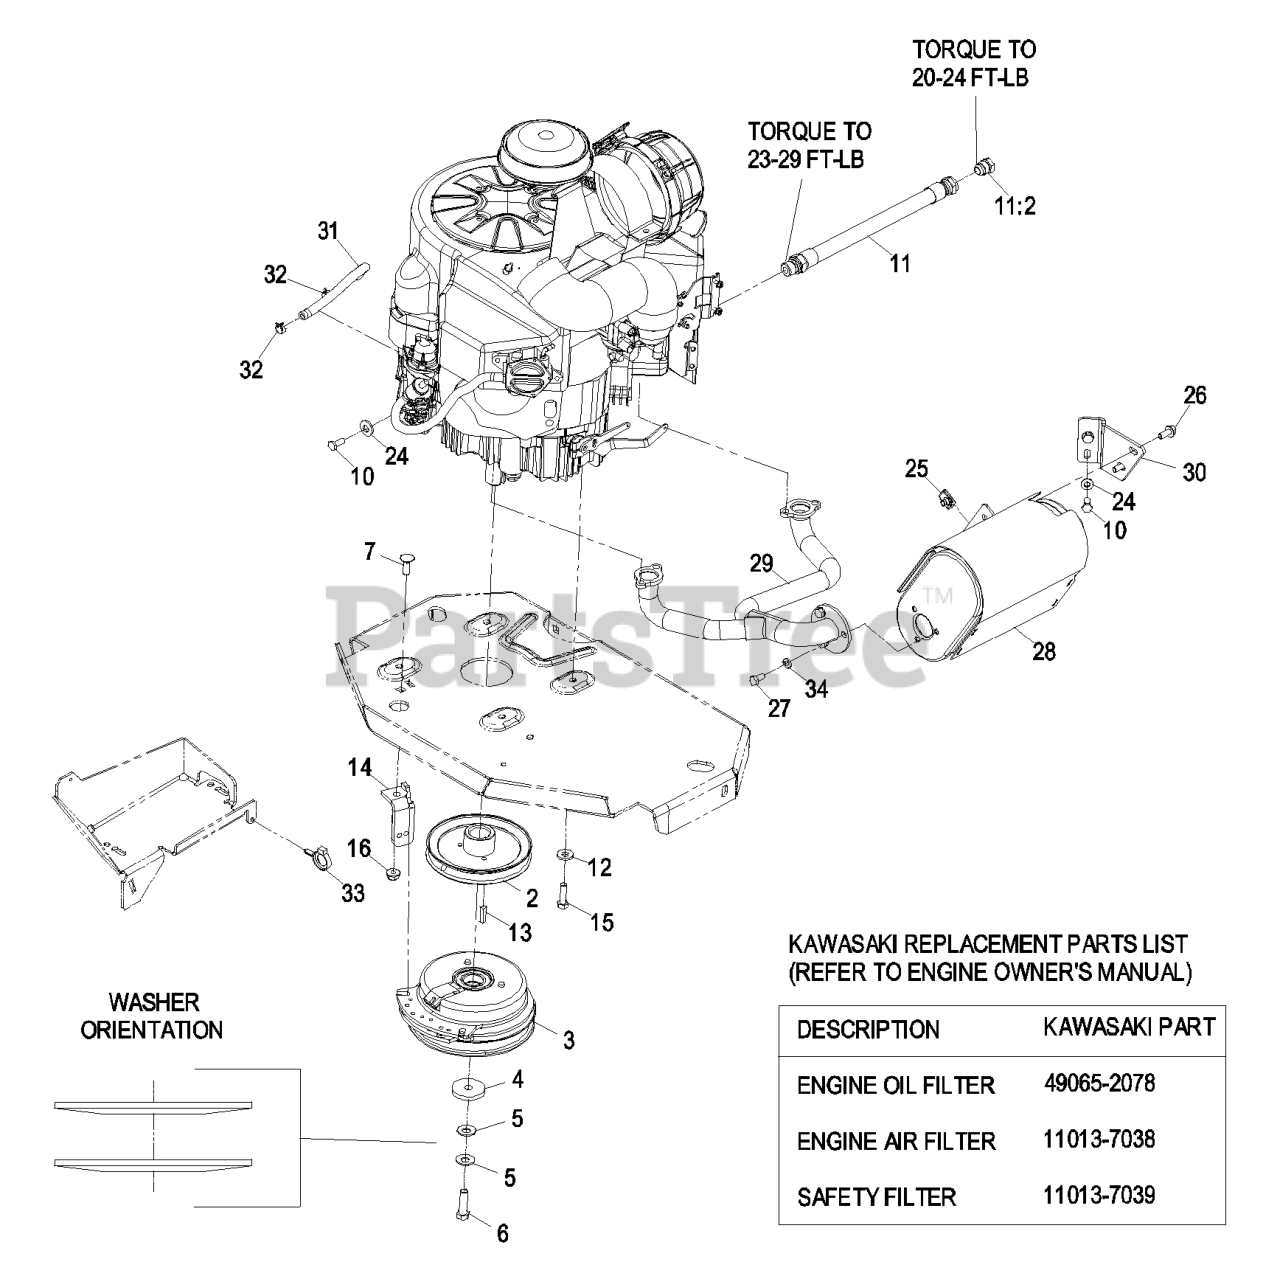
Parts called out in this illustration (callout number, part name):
2	SHEAVE
4	WASHER-CLUTCH
5	WASHER-SPRING
6	SCREW-HH 7/16-20 X 1 1/2 W/LOCTITE
7	SCREW-CARR
10	SCREW-HH
12	WASHER-BELLEVILLE
14	ANCHOR-CLUTCH
15	SCREW-HH
16	NUT-HF, NI
24	WASHER-SPRING
26	SCREW-HHF
27	SCREW-HH
28	MUFFLER-ENGINE
30	BRACKET-MUFFLER
31	HOSE-FUEL
32	CLAMP-HOSE
33	CLAMP-HOSE
34	WASHER-LOCK
